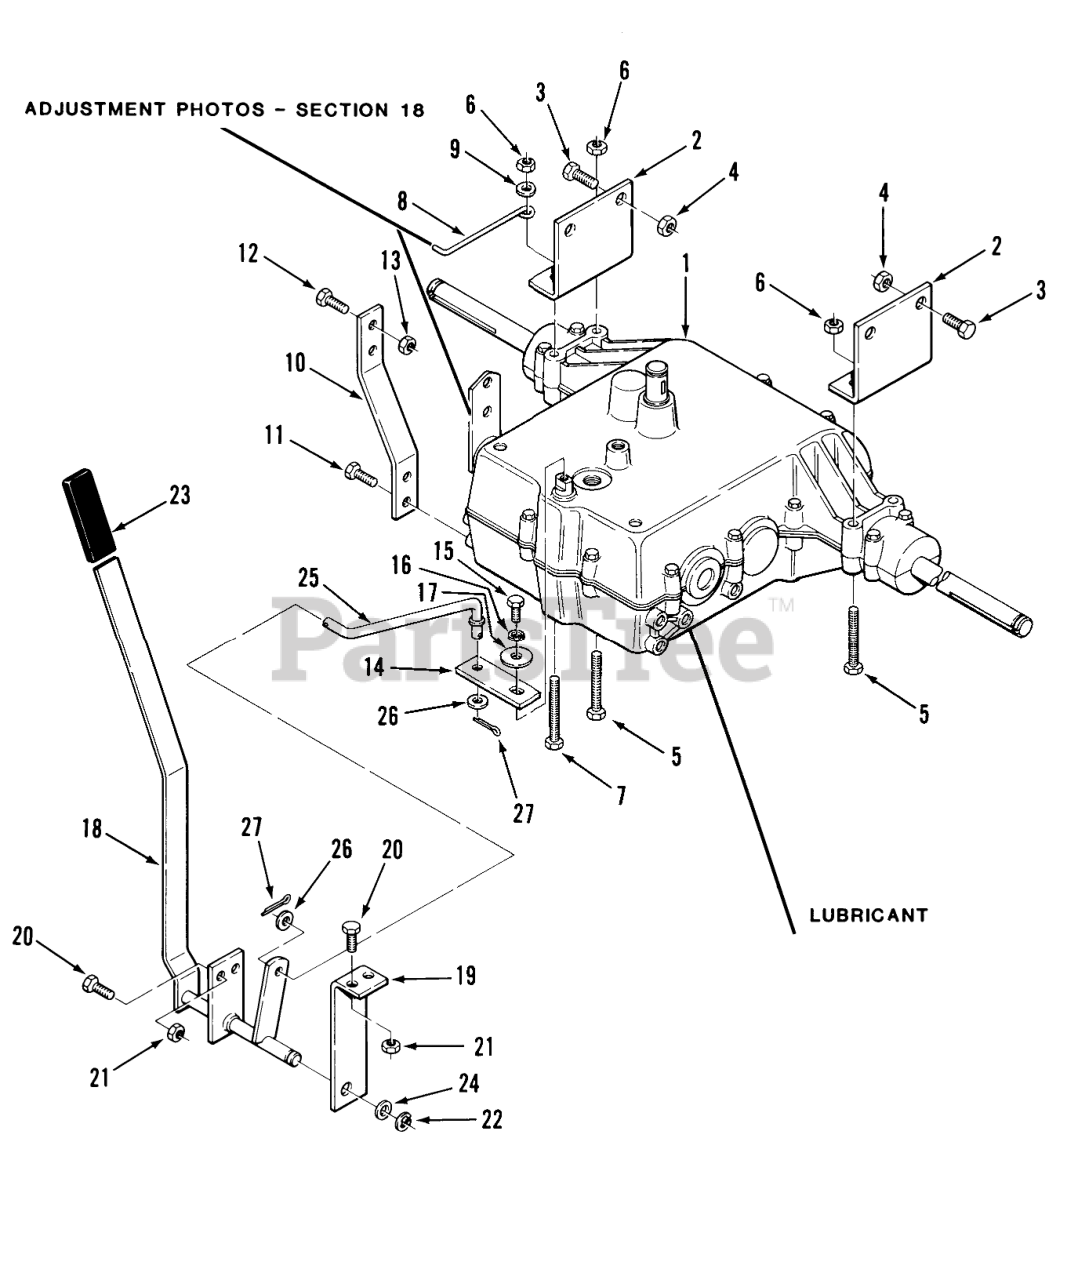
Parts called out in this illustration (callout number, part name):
1	Transmission Peerless Model 829
2	Bracket-Rear Axle
3	Bolt
4	NUT
5	HHCS
6	Nut
7	Pin-Cotter
8	Brake Stop Rod
9	WASHER 5/16 SAE
10	TORQUE STRAP R
11	Screw
12	Bolt
13	Nut
14	LEVER LOWER SHIFT
15	Bolt 1/4-28 X 7/8
16	Washer
17	WASHER
18	Shift lever Assy
19	SUPPORT SHIFT
20	Bolt
21	Nut
22	RING-RETAINING
24	Washer
25	ROD - LOWER SHIFT
26	WASHER 5/16 SAE
27	Cotter Pin
